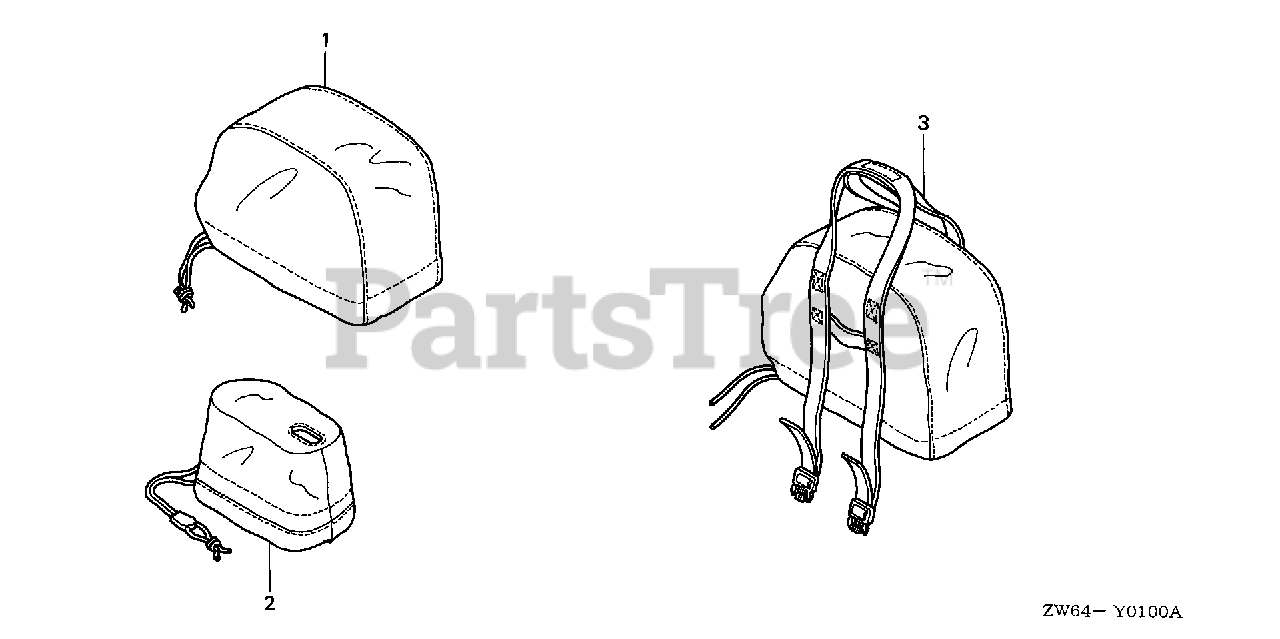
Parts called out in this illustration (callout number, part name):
1	COVER KIT, ENGINE (BF2)
2	COVER KIT, PROPELLER
3	BAG KIT, ENGINE CARRIER
